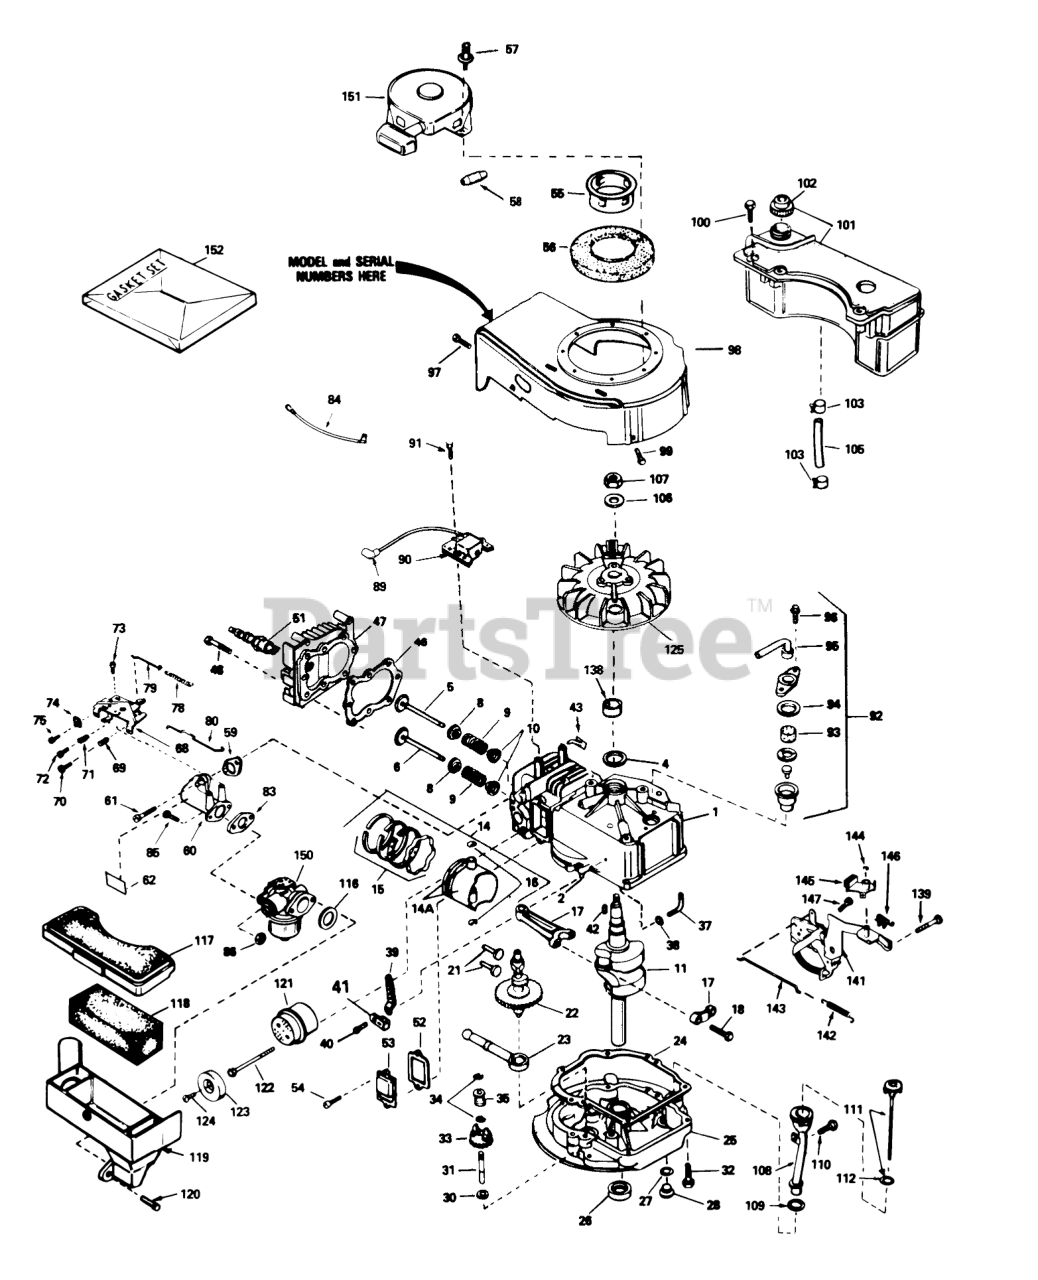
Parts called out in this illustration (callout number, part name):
1	Cylinder Assy. (Incl. #2 & 4)
2	Pin-Dowel
4	Seal-Oil
5	Valve-Intake (Std.) (Incl. #10)
5	VaIve-Intake (1 /32" Oversize) (Incl. #10)
6	Valve-Exhaust (Std.) (Incl. #10)
6	Valve-Exhaust (1 /32" Oversize) (Incl. #10)
8	Cap-Upper Valve Spring
9	Spring-Valve
10	Cap-Valve, Spring
11	Crankshaft
14	Piston-Pin & Ring Assy. (Std.) (Incl. #14A, 15 & 16)
14	Piston-Pin & Ring Assy. (.010 Oversize) (Incl. #14A, 15 & 16)
14	Piston-Pin & Ring Assy. (.020 Oversize) (Incl. #14A, 15 & 16)
14A	Piston & Pin Assy. (Std. ) (Incl. #16)
14A	Piston & Pin Assy. (.010 Oversize) (Incl. #16)
14A	Piston & Pin .020 O.S. (Incl. Ref. #25)
15	Piston Ring Set Std.
15	Piston Ring Set .010 O.S.
15	Piston Ring Set .020 O.S.
16	Ring-Retaining, Piston Pin
17	Rod Assy.-Connecting (Incl. #18)
18	Bolt-Rod, Connecting
21	Lifter-Valve
22	Camshaft(Mech.Comp. Release)
23	Oil Pump ASM
24	Gasket, Mounting
25	Flange Assy.-Mounting (Incl. #26, 27, 28 & 31)
26	Seal Oil
27	Gasket-Oil Drain
28	Plug Oil Drain
30	Washer-Flat
31	Shaft-Governor
32	Screw (1/4-20 x 1-1/4)
33	Gear Assy.-Governor (Incl. #30)
34	Ring-Retaining
35	Spool-Governor
37	Rod-Governor (Incl. #38)
38	Washer-Flat
39	Governor Lever
40	Screw
41	Clamp-Lever, Governor
42	Key-Flywheel
43	Clip-Wire
46	Gasket-Cylinder Head
47	2025A67 ADD.ASSEMBL
48	Screw (5/16-18x1-1/2)
51	Plug, Spark (Autolite 458, Champion J-19LM or equiv.)
52	Gasket-Breather
53	Cover-Valve
55	Cup-Starter
56	Screen-Starter
57	Pop Rivet (Can be purchased locally)
58	Retainer-Starter Rope
59	Gasket-Intake
60	Pipe-Intake (Incl. #59)
61	Screw (1/4-20 x 1)
62	Decal-Primer
68	A Control Assy.-Remote Speed (Incl. #69-72)
69	61709/GIL1515A/95-5
70	Screw
71	Spring-Compression
72	Screw
73	Screw (10-24 x 9/16)
74	Conduit
75	Screw (10-32 x 3/8)
78	Spring Governor
79	2035A67 ADD.ASSEMBL
80	Link-Throttle
83	Gasket
84	Ground Wire
85	Screw (1/4-28 x 7/8)
86	Nut and Lock Washer (1/4-28)
89	Cover-Spark Plug
90	Lamination & Coil Assy. (Solid State) (Incl. #89)
91	Screw
92	Breather Assy. (Incl. #93-96)
93	Element-Breather
94	Gasket-Breather
95	Tube, Breaker
96	Screw (10-24 x 9/16)
97	Screw (10-24 x 9/16)
98	Housing-Blower
99	Screw (1/4-20 x 1/2)
100	Screw (10-32 x 35/64)
101	Tank Assy.-Fuel (Incl. #102)
102	Cap-Fuel
103	Clamp-Line, Fuel
105	Line-Fuel
106	Washer-Belleville
107	Nut-Flywheel
108	Tube-Oil Fill
110	Screw (10-32 x 1/2)
111	Dipstick-Oil (Incl. #112)
116	Gasket-Cleaner, Air
117	Cover Air Cleaner
118	Filter-Air Cleaner
119	Body Air cleaner
121	Muffler (Incl. #122)
123	Cover-Muffler
124	Screw
125	Flywheel
139	Screw (1/4-20 x 3/8)
141	Bracket Assy.
142	Spring-Extension
143	Link-Control
144	Ring-Retaining
145	Lever-Brake
146	Terminal
147	Screw-Hex. Hd.
150	Carburetor (Incl. #83)
151	tarter-Rewind
152	Gasket Set (Incl. Items Marked )
